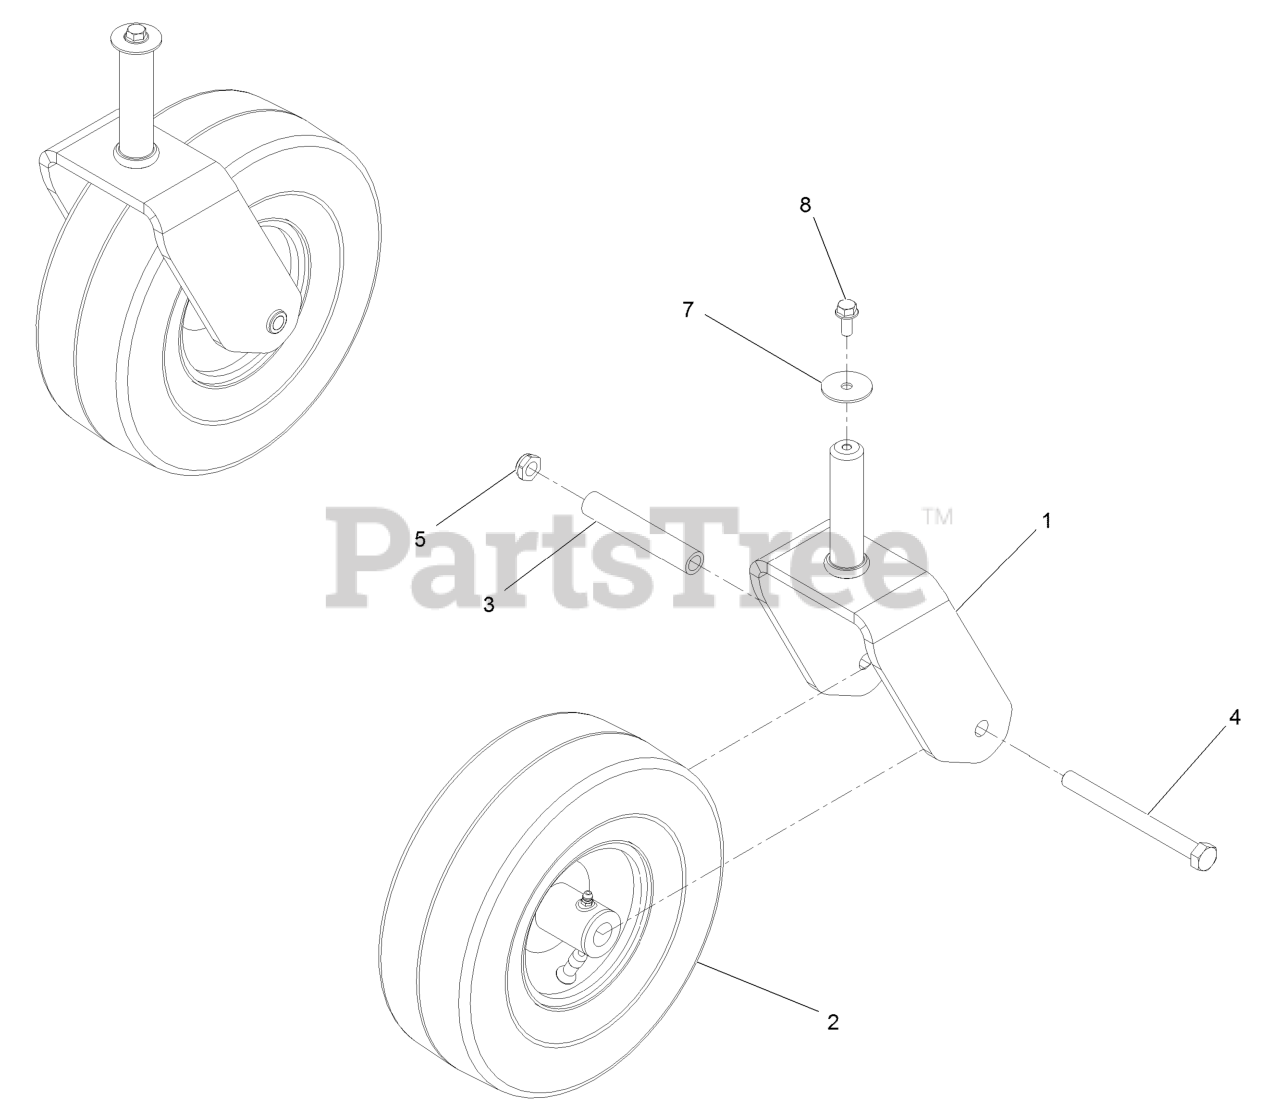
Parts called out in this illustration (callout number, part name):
1	Fork-Caster [red]
2	Tire And Wheel ASM (C S T)
3	Bushing-Spanner
4	Screw-HH 1/2-13 X 5 1/2
5	Nut-Nyloc 1/2-13 Thin
7	Washer-Flat
8	Screw-HH Flg 5/16-18 X 3/4
